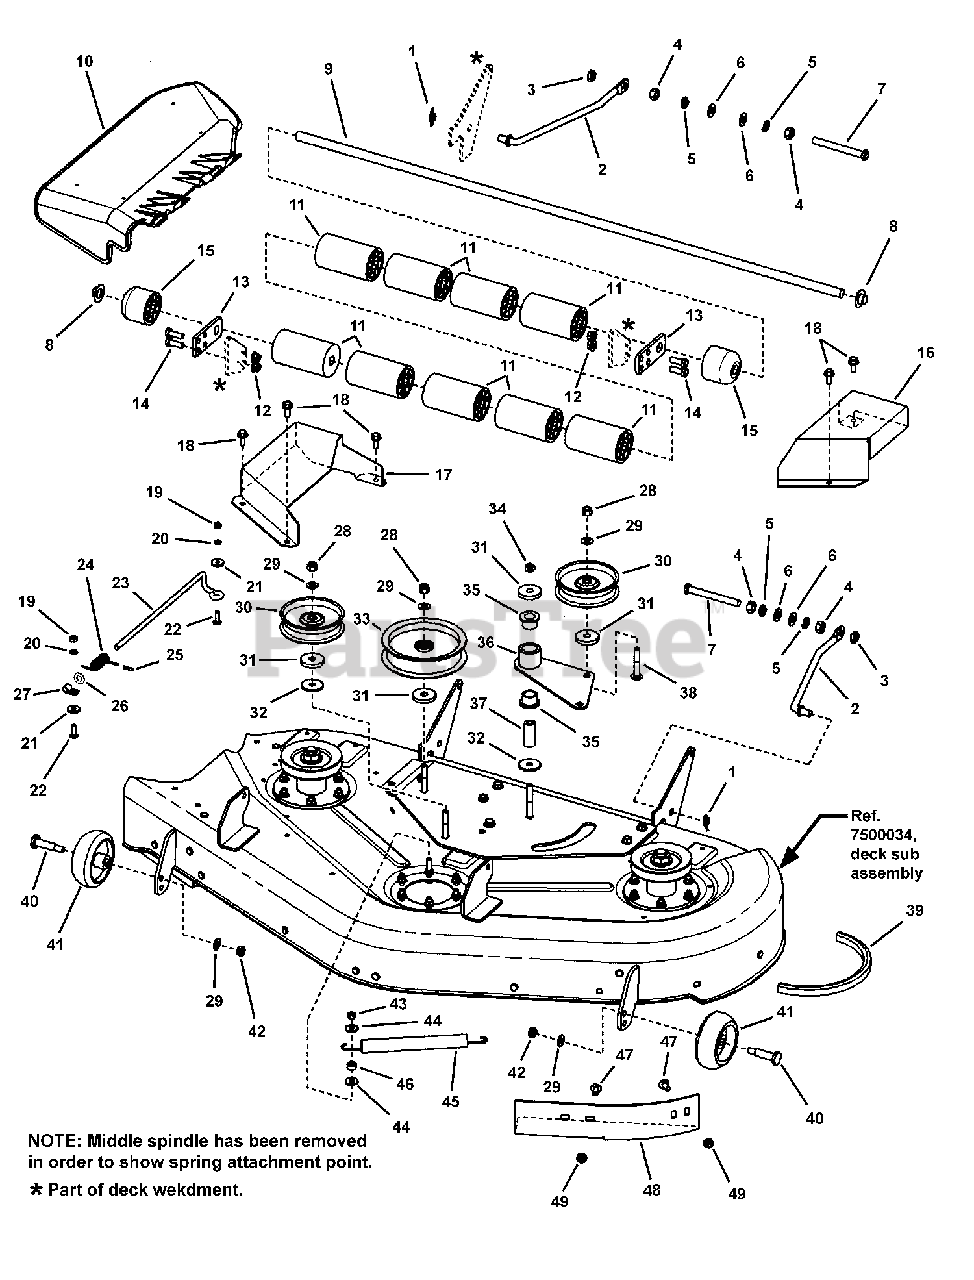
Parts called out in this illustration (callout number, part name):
1	PIN, Cotter, 1/2 SELF, YZ
2	ROD, Stabilizer
3	NUT, Hex Center Lock Jam, 7/16F GR5 YZ
4	NUT, Hex, 7/16F GR5 BZ
5	WASHER, Lock, .445X.776X.1 YZ
6	WASHER, .47X.92X.065 YZ
7	CAPSCREW, Hex Head, 7/16F X4-1/4 GR5 YZ
8	NUT, Push For 5/8 Diameter Stud Capped Black
9	SHAFT, Roller, 44, Black
10	DEFLECTOR, Black
12	NUT, Hex Flange Lock, 3/8C YZ
13	BAR, Roller, 44/50, Black
14	CAPSCREW, Hex Head, 3/8C X1 GR5 YZ
15	ROLLER, Rounded
16	COVER, Spindle, RZT 44/50", Orange, LH
17	COVER, Spindle, RZT 44/50", Orange, RH
18	CAPSCREW, Hex Head Flange Taptite, 5/16C X3/4 YZ
19	NUT, Hex 1/4-20 Black 588514
20	LOCKWASHER, Spring 1/4 Black
21	WASHER, 1/4 Black
22	CARRIAGE BOLT, 1/4-20X 7/8 G5 Black
23	ROD, Deflector, Front
24	SPRING, Torsion
26	WASHER, 5/16 Black
27	CLAMP, Wire, 5/16 Diameter . (1) .281 Hole Black
28	NUT, Hex, 3/8C, Nylock YZ
29	WASHER, 3/8 SAE YZ
30	PULLEY, Flat Idler, 4"
31	WASHER, .468X1.625X.25 YZ
32	WASHER, .406X1.5X.120 YZ
33	PULLEY, Flat Idler 5.0 X
34	NUT, Hex Center Lock, 3/8C GR5 ZP
35	BEARING, Powdered Metal
36	WELD, Hinge Pivot
37	SPACER, Idler, Yellow
38	CARRAIGE BOLT, 3/8-16 X 2-1/4, GR5
39	BELT, RZT, 44", EL 137.75, B SEC.
40	BOLT, Shoulder, 3/8F X.62, 1/2 DIA, YZ
41	WHEEL, Gage 4 X 1.5
42	NUT, Hex Center Lock, 3/8F GR5 YZ
43	NUT, Hex Center Lock, 5/16C GR5 YZ
44	WASHER, .375X.875X.083 YZ
45	SPRING, Idler Primary
46	SPACER, .625 OD X .340 ID X .31 L
47	CARRAIGE BOLT, 5/16C X3/4 GR5 YZ
48	SHORT BLOWOUT BAFFLE PLAIN
49	NUT, Hex Flange Lock, 5/16C GR5 YZ
